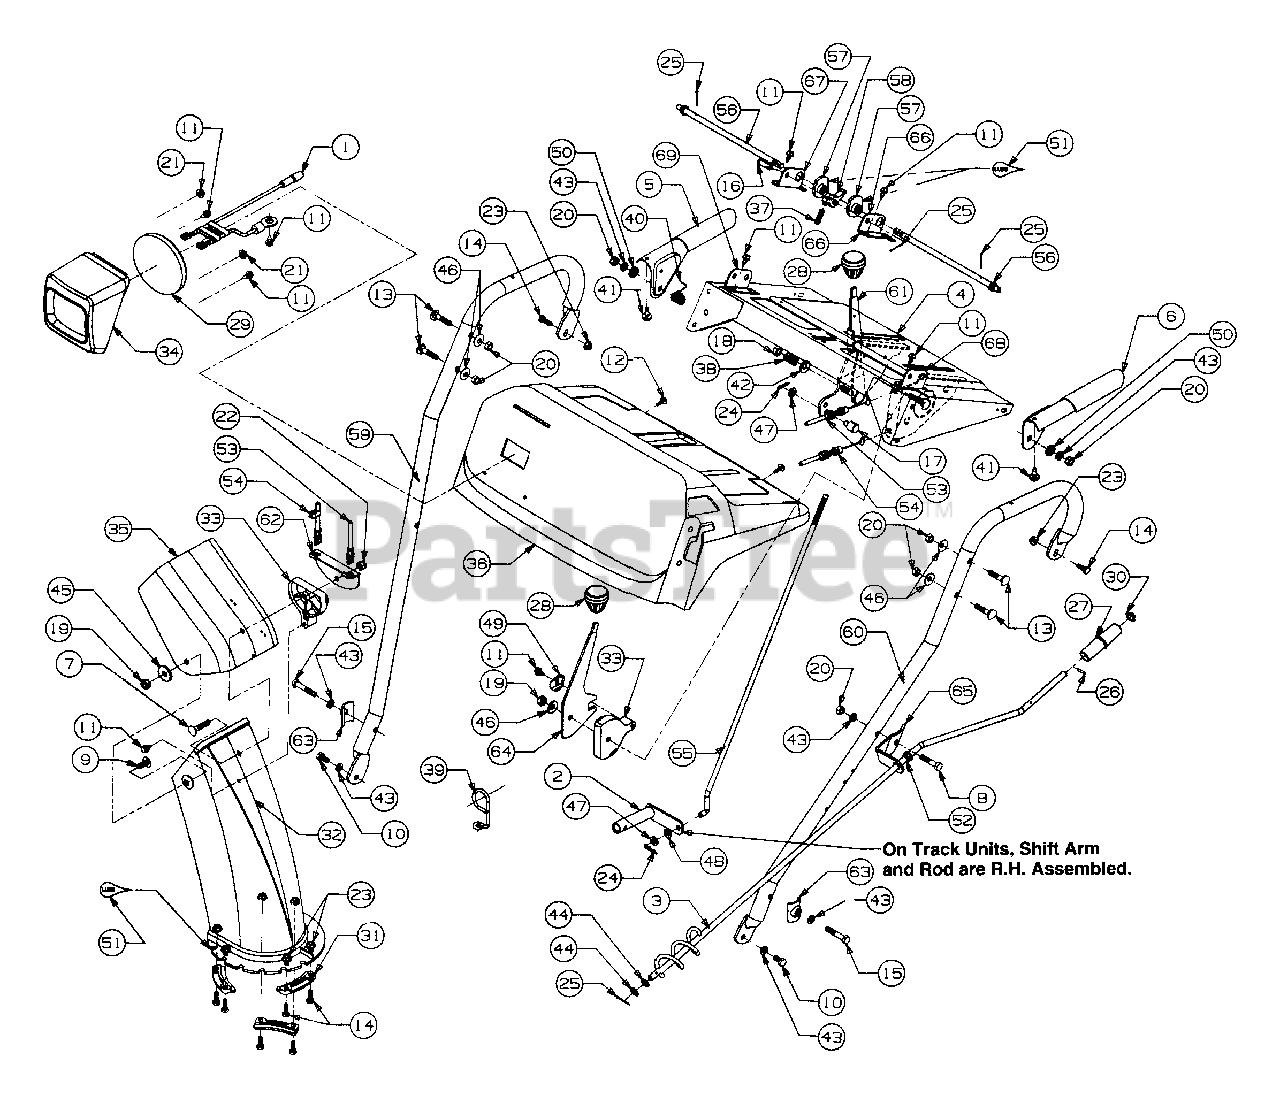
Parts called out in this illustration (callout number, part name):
1	Harness Light
3	Crank, Chute
6	Handle, Engagement L.H.
7	Bolt Carriage
8	Screw, Hex
9	Bolt, Carriage
10	Hex Screw
11	Hex Screw
12	Screw Hex
13	Bolt, Curved Carriage
14	Hex Cap Screw
15	Hex Screw
16	Pin, Clevis
17	Ferrule, Engagement
18	Hex Lock Nut
19	Nut, Hex Lock
20	Nut, Hex
21	Nut, Self Threading
22	Hex Lock Nut
23	Nut, Lock, Hex, Flanged
24	Pin, Cotter
25	Pin, Cotter
26	Roll Pin
27	Knob, Chute Crank
28	Knob, Shift
29	Headlight
30	Cap, Push
31	Chute, Flange Keeper
32	Lower Chute, 5" Dia. Plastic
33	Cable Guide
34	Bezel Headlight
35	Chute, Upper 5.0 Dia. Remote
36	Handle w/Tilt
37	Spring
38	Spring
39	Cable Control Wire
40	Spring
41	Bumper
42	Washer, Bell
43	Lock Washer
44	Flat Washer
45	Washer
46	Washer, Bell
47	Washer, Flat
48	Washer
49	Washer
50	Washer
51	Lubricant
52	Bushing, Plastic
53	Cable, Chute Deflector
54	Cable, Chute Deflector w/Clip
55	Rod, Shift
56	Rod, Cam
57	Cam Handle Lock
58	Pawl Handle Lock
63	Handle Tab
